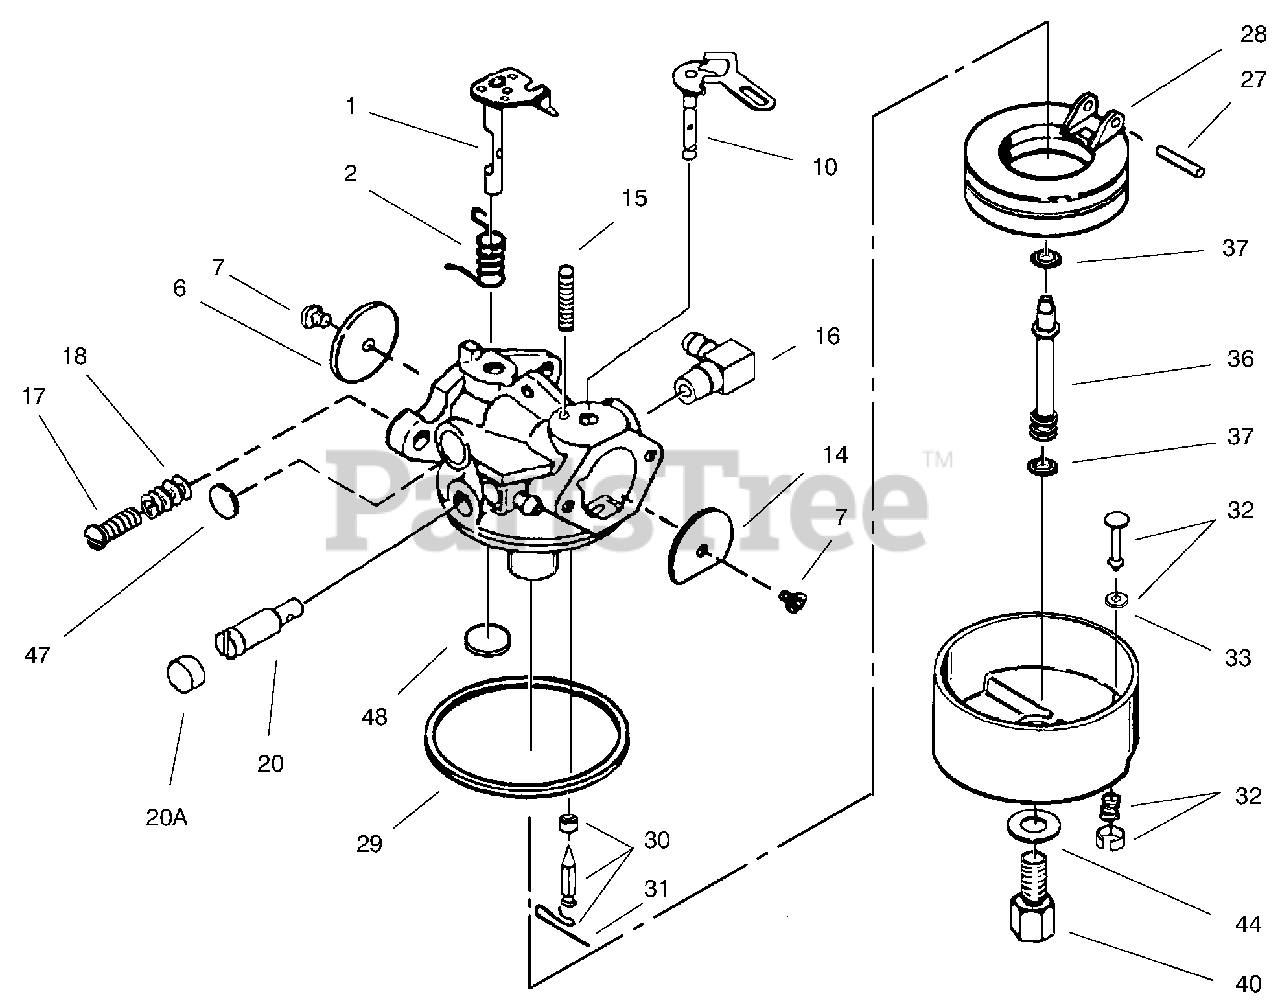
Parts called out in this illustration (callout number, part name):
1	Shaft & Lever Assembly
2	Throttle Shaft & Lever Asm.
6	Throttle Shutter
7	Screw-Shutter
10	Choke Shaft & Throttle Asm.
14	Shutter-Choke
15	Spring-Choke Positioning
16	Fuel Fitting
17	Screw-Idle
18	Spring-Tension
20	Screw-Idle Restrictor
20A	Cap-Idle Restrictor Screw
25	Float Bowl Asm. (Incl. Ref. # 32, 33)
27	Shaft-Float
29	ORing-Float Bowl
30	Inlet Needle-Seat & Clip (Incl. Ref. # 31)
31	Clip-Spring
32	Bowl Drain Asm.
33	Gasket-Drain Plunger
36	Main Nozzle Tube
37	ORing-Main Nozzle Tube
40	Nut-High Speed Bowl
44	Bowl Nut Washer
47	Welch Plug-Idle Mixture Well
48	Welch Plug-Atmospheric Vent
